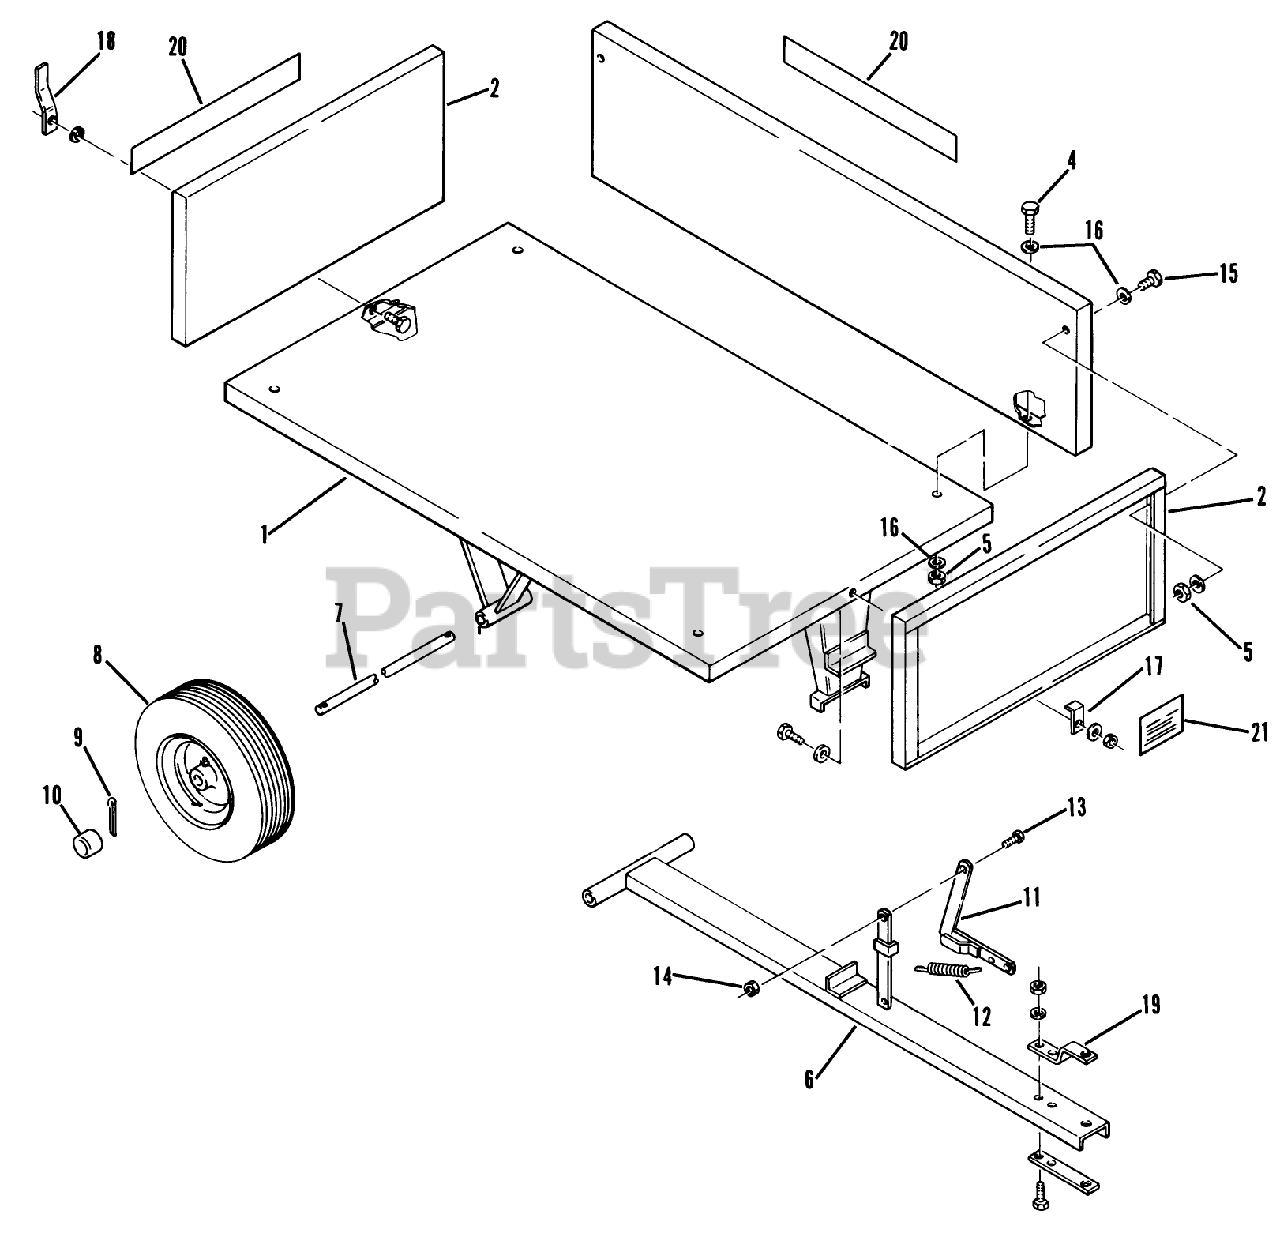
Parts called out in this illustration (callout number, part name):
1	Bed Assembly
2	Front and Rear Gate
3	Side Gate
4	BOLT
5	NUT
6	Drawbar Assembly
8	Wheel Assembly (6.50 x 8-16)
9	Cotter Pin
10	HUB CAP
11	Latch Assembly
12	SPRING
13	Bolt
14	Nut
15	Bolt
16	Washer
17	Latch-Front Gate
18	Latch-Rear Gate
19	CLEVIS-BAR
20	Decal
21	Decal,"Weight Limit"
